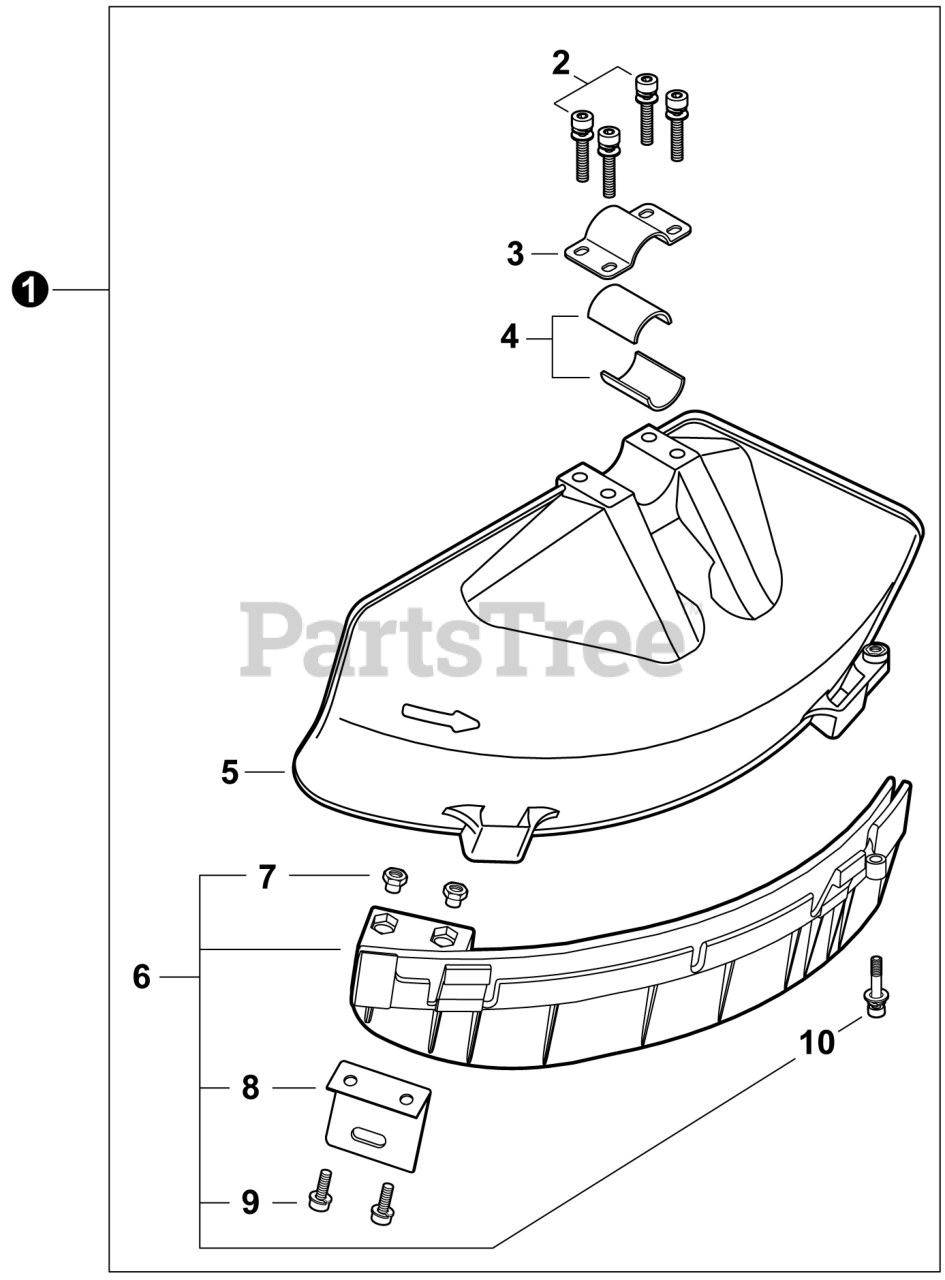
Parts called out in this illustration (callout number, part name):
1	SHIELD KIT, DEBRIS
2	BOLT M5x45
3	CLAMP, UPPER
4	SPACER 24
5	SHIELD, DEBRIS - BLADE
6	EXTENSION ASSY, DEBRIS SHIELD
9	BOLT 5x16
10	BOLT M5x22
